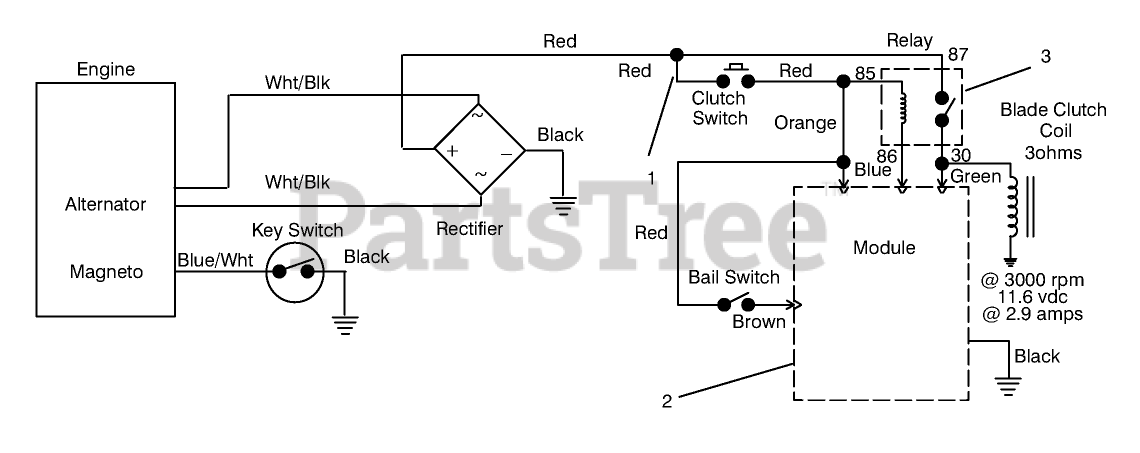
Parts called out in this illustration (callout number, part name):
1	WIRE HARNES - KAWASAKI
2	MODULE
3	RELAY
